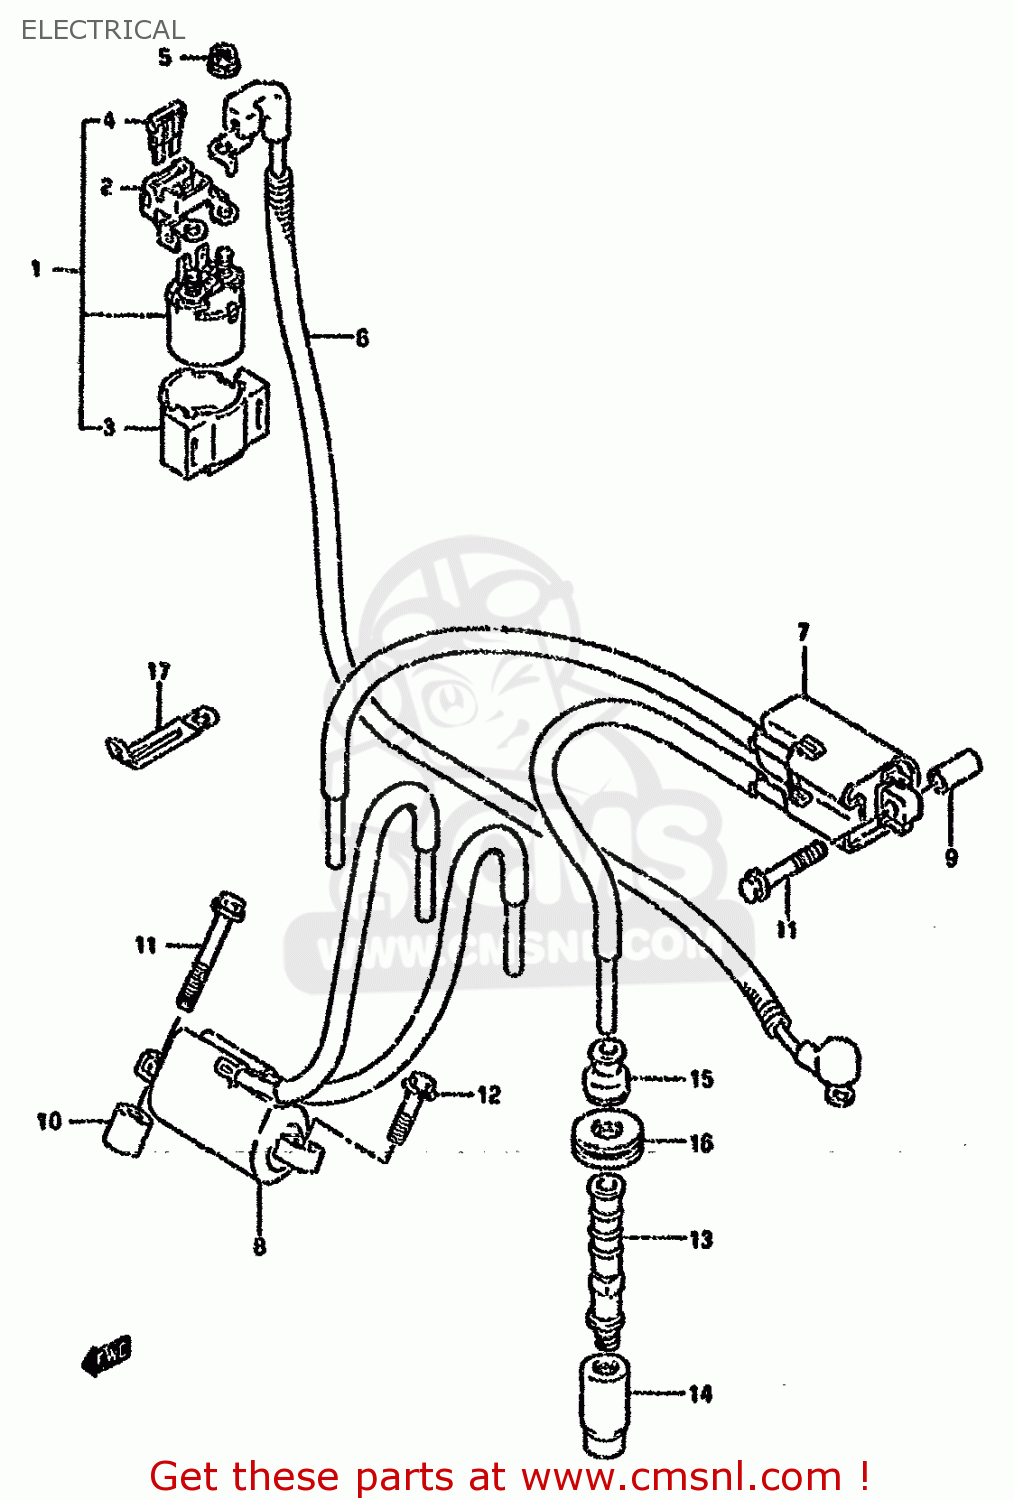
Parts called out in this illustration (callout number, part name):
1	RELAY ASSY,STARTING MOTOR
2	TERMINAL,RELAY
3	BRACKET,STARTING MOTOR RELAY
4	FUSE (30A)
5	NUT
6	WIRE,STARTER MOTOR
7	COIL ASSY,IGNITION
8	COIL ASSY,IGNITION
9	SPACER
10	SPACER,IGNITION COIL 1
11	BOLT,COIL
12	BOLT
13	CAP,SPARK PLUG
14	SEAL,SPARK PLUG
15	SEAL,HIGH TENSION CORD
16	COVER,SPARK PLUG CAP
17	CLAMP
